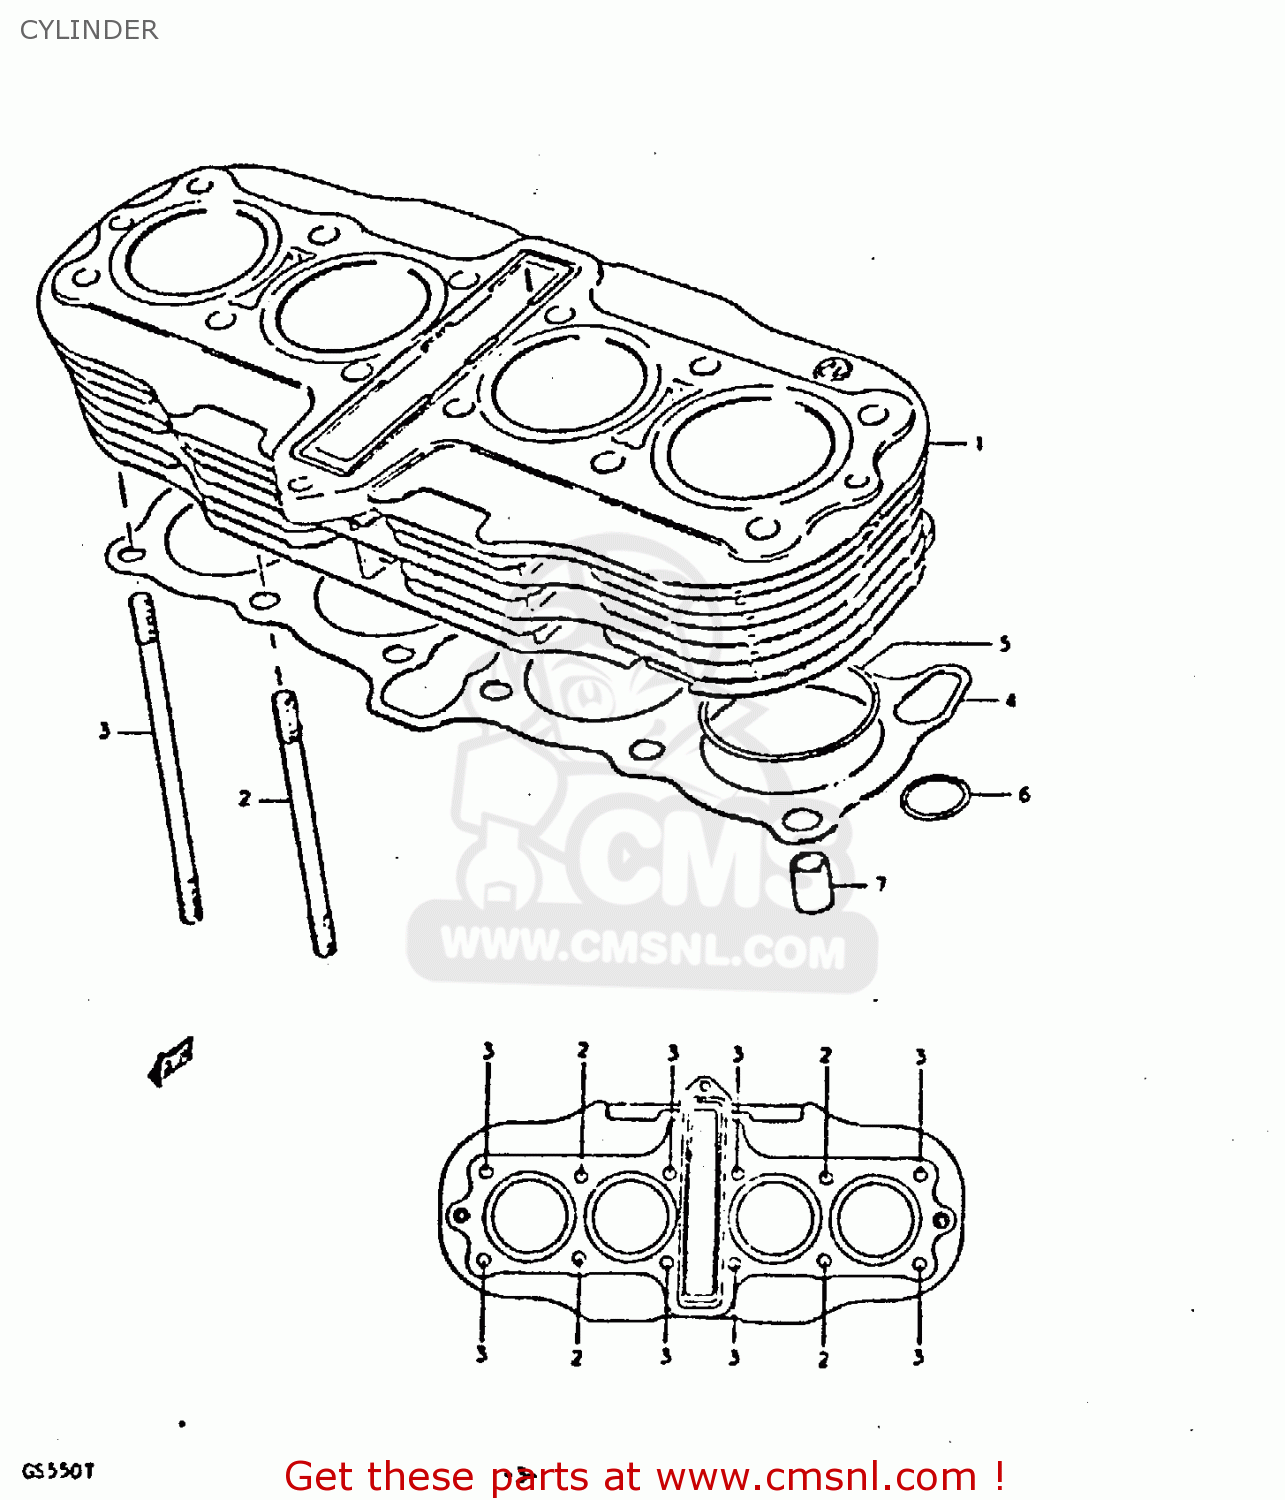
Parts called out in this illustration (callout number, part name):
1	CYLINDER
2	BOLT,STUD
3	BOLT,STUD
4	GASKET,CYLINDER (MCA)
5	O RING(D:2,ID:61)
6	INVALID PARTNUMBER
7	PIN
